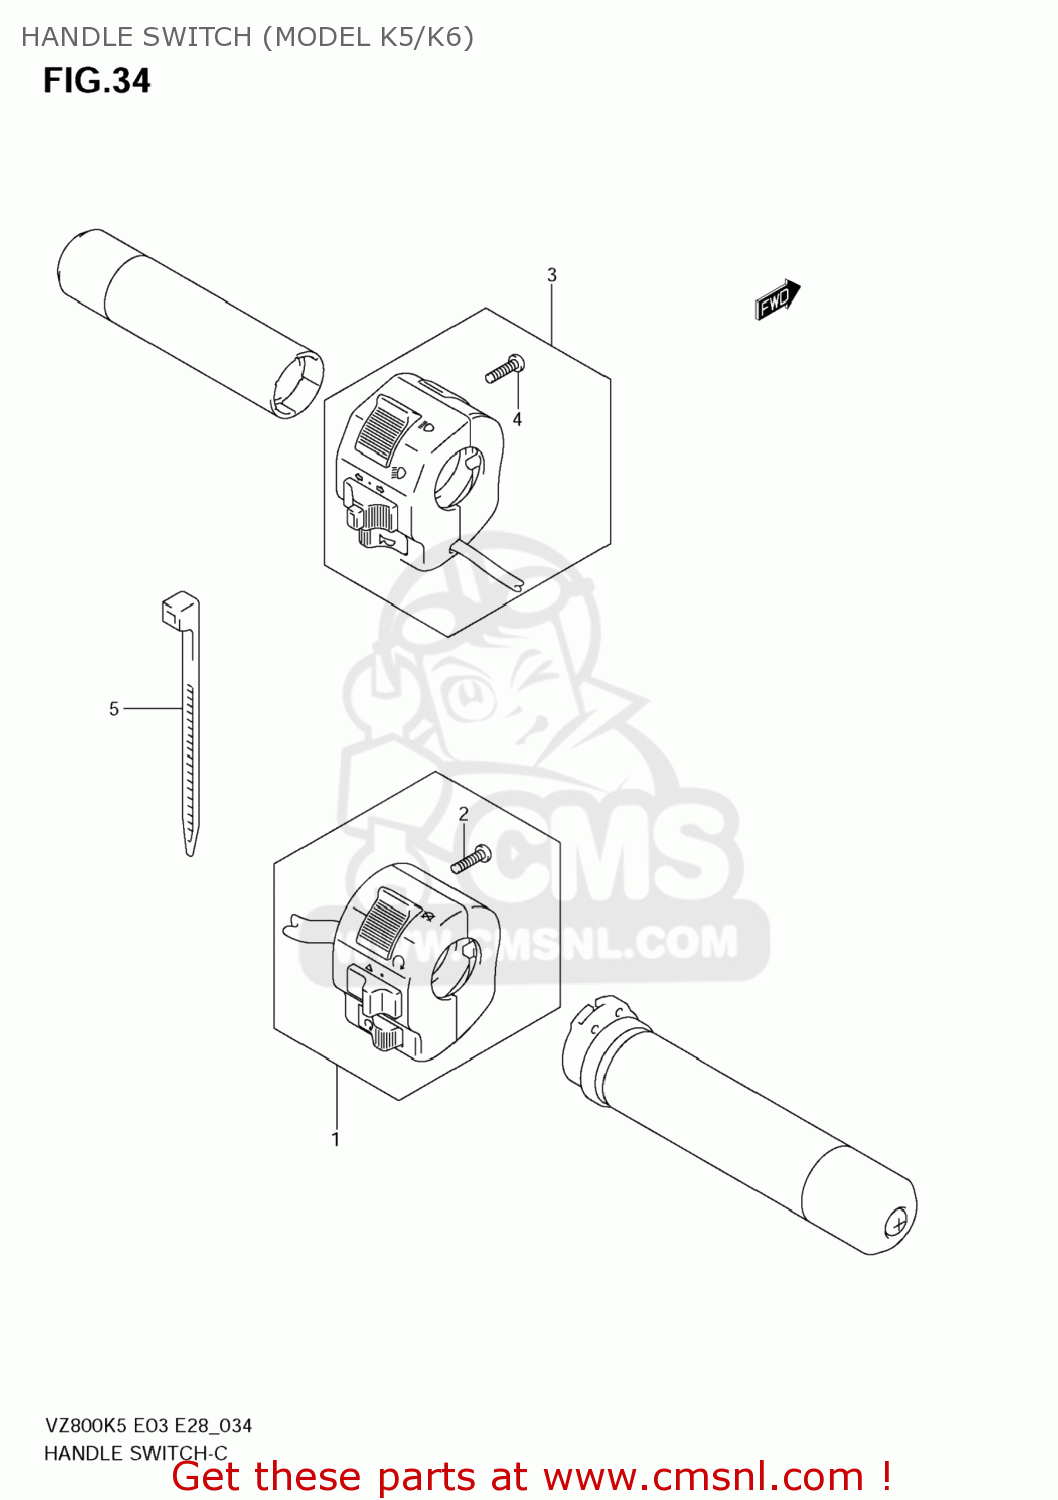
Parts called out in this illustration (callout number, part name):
1	SWITCH ASSY,HANDLE,R
2	SCREW(5X16)
3	SWITCH ASSY,HANDLE,L
4	SCREW(5X16)
5	CLAMP(L:145)
